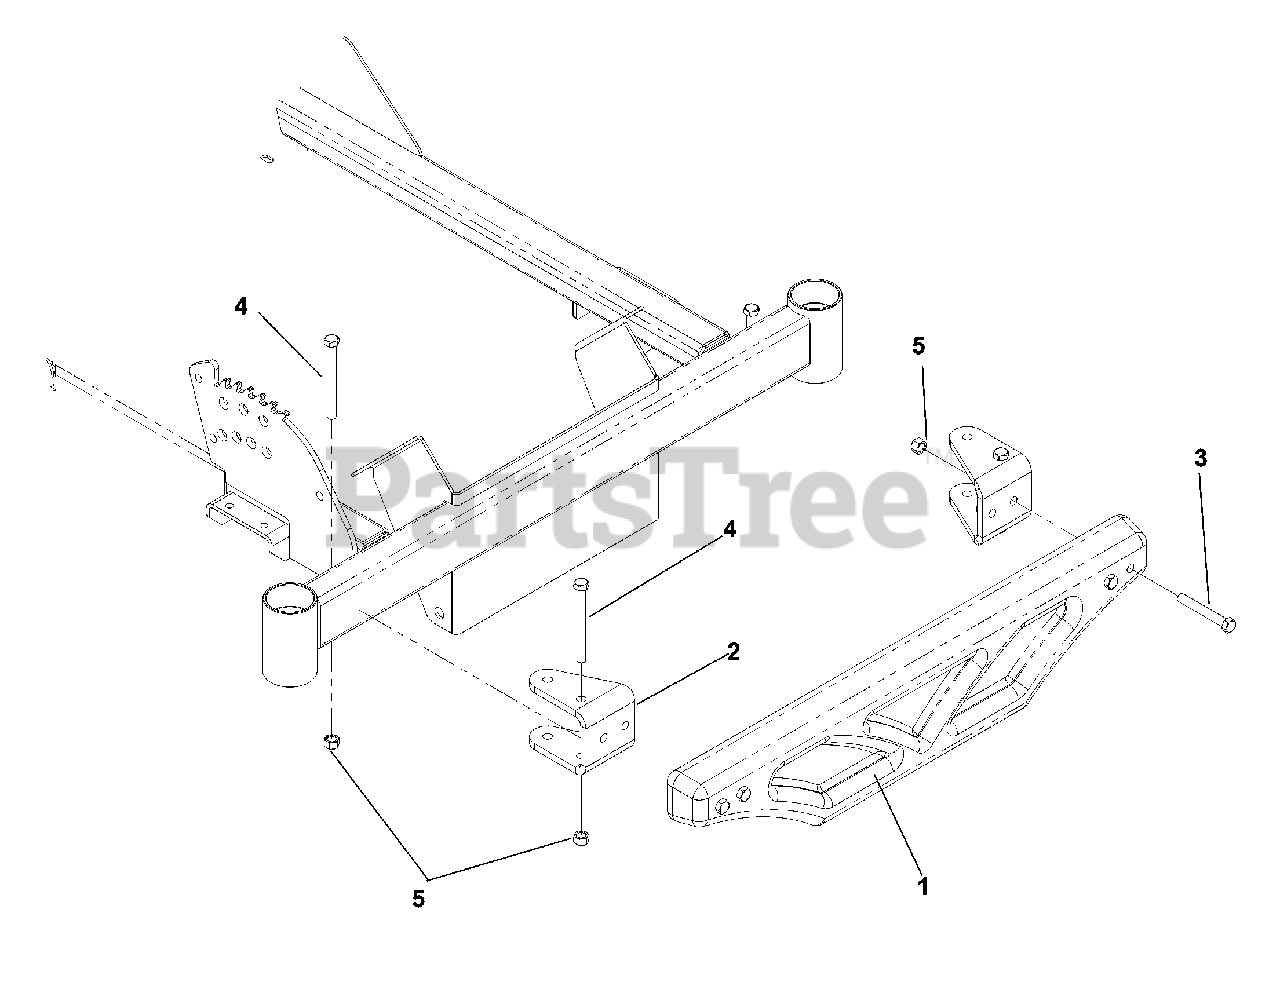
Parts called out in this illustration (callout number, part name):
1	CAST WEIGHT
2	BRACKET, WEIGHT
3	HEX SCREW 3/8-20 X 2.75
4	HCS3/8-16.X
5	NUT 3/8-16 NYLOC
